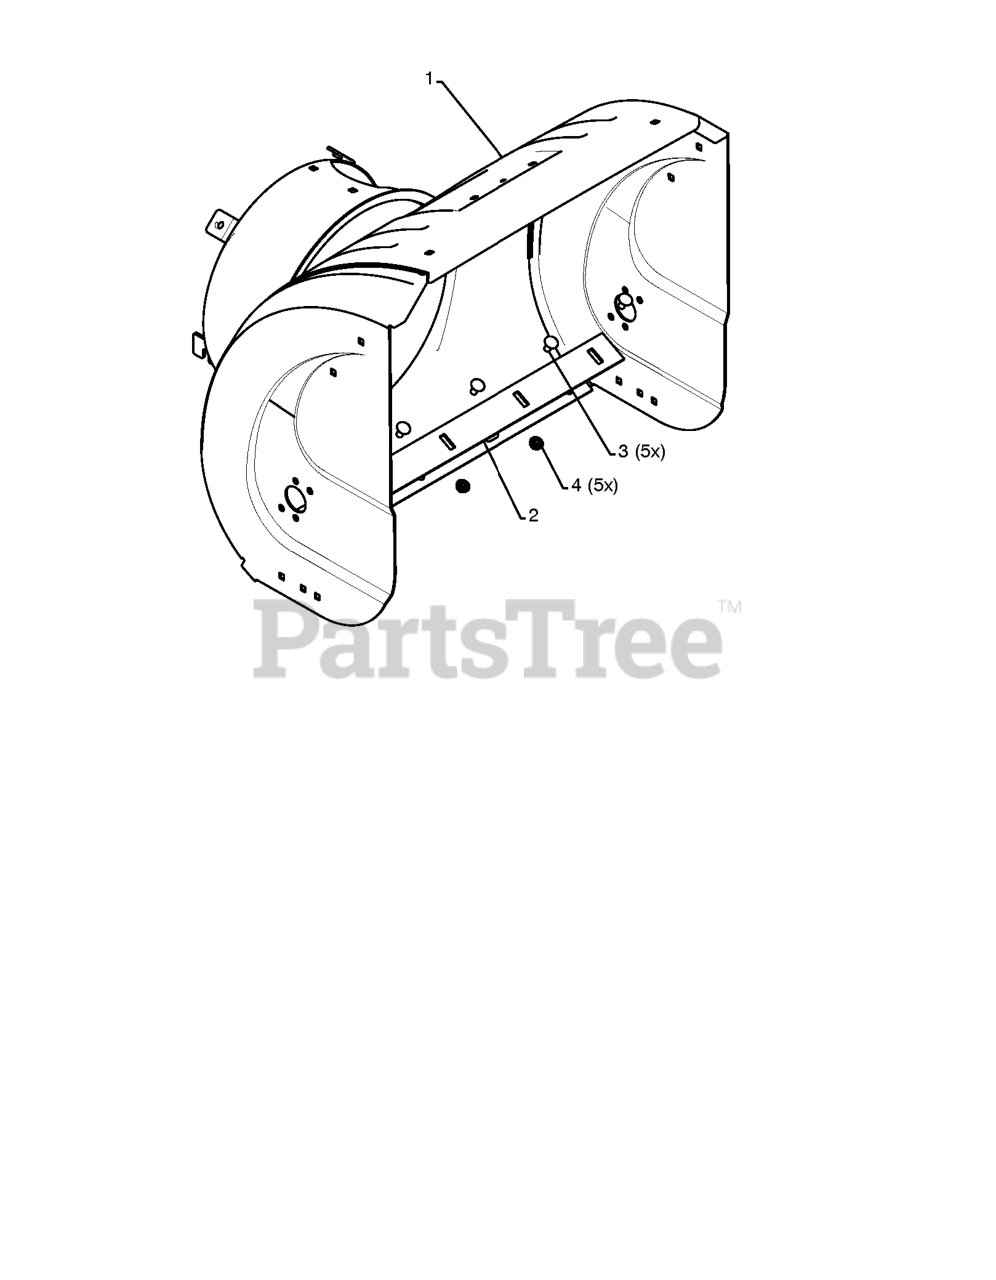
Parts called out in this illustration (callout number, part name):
1	AUGER HOUSING
2	BAR, SCRAPER
3	BOLT
4	NUT.FLANGE.5/16
